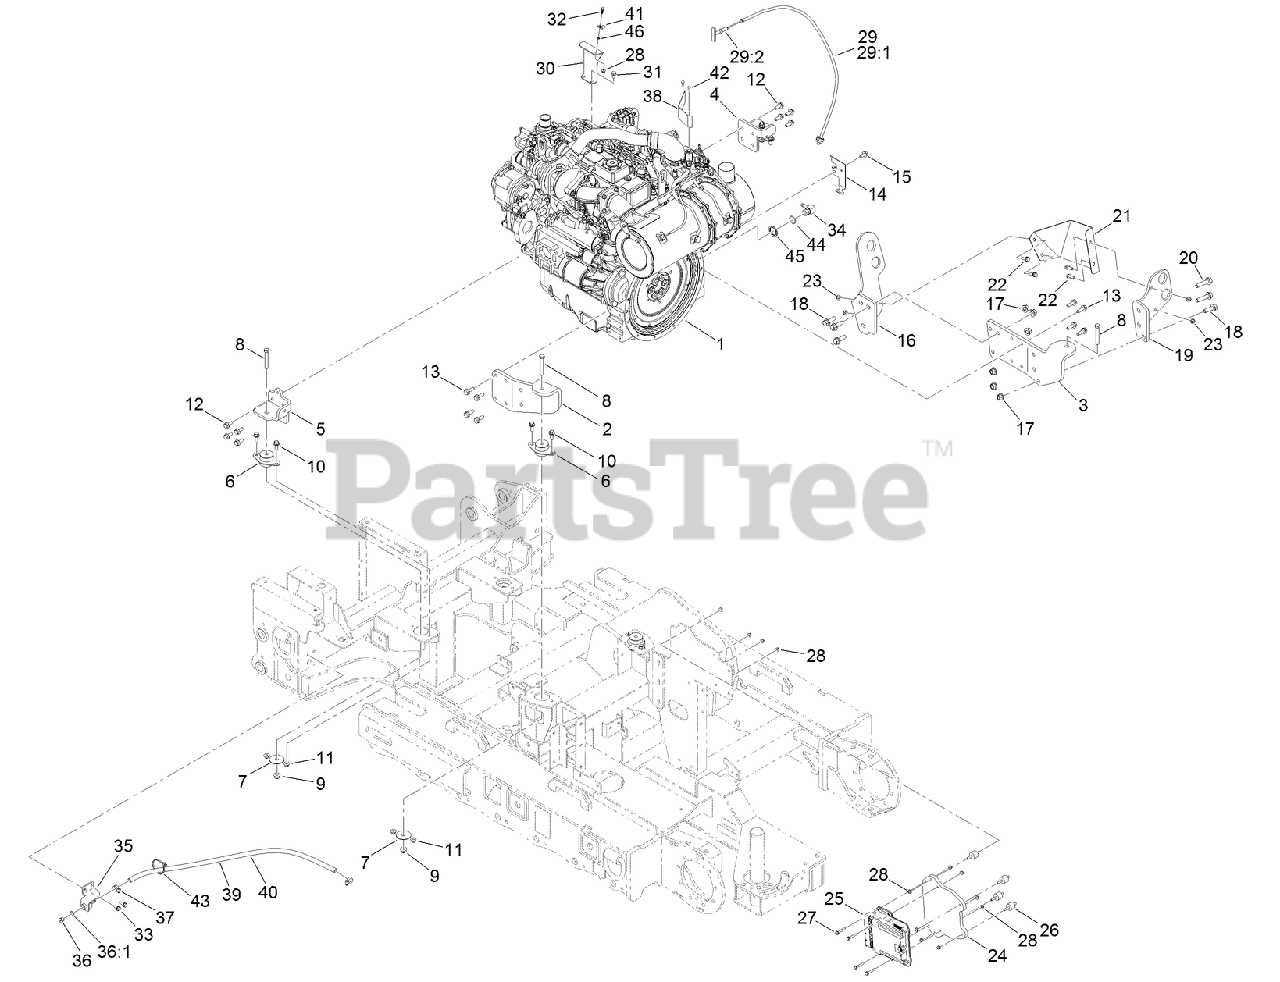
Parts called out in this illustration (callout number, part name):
1	ENGINE ASM
2	BRACKET-ENGINE MOUNT, RH FRONT
3	BRACKET-ENGINE MOUNT, LH FRONT
4	BRACKET, LH REAR
5	BRACKET, RH REAR
7	WASHER-SNUBBING
8	SCREW-HH
9	NUT-HF, NI
10	SCREW-HHF
11	NUT-HF, NI
12	SCREW-HHF
13	SCREW-HHF
14	BRACKET-HARNESS
15	SCREW-HHF
16	BRACKET-BULKHEAD, UPPER
17	NUT-LOCK
18	SCREW-HHF
19	BRACKET-BULKHEAD, LOWER
20	SCREW-HHF
21	BRACKET-SHIELD, HEAT
22	SCREW-HHF
23	NUT-HF, NI
24	PLATE-WEIGHT, ECU
25	CONTROLLER-ENGINE
26	MOUNT-ISOLATOR
27	SCREW-HHF
28	NUT-HF
29	OIL DIPSTICK ASM
29:1	TUBE-DIPSTICK
29:2	DIPSTICK-OIL, ENGINE
30	SHIELD-FUEL HOSE
31	SCREW-HHF
32	SCREW-HHF
33	SCREW-HWH
34	FITTING-BARBED-90
35	PLUG-OIL
36	PLUG-HEX, HOLLOW
36:1	O-RING
37	CLAMP-HOSE
38	PLATE-SENSOR, DPF
39	HOSE-OIL DRAIN
40	CONDUIT-FUEL LINE, SPLIT
41	CLAMP-R
42	SCREW-HHF
43	TIE-CABLE
44	O-RING
45	WASHER-SEAL
46	WASHER-LOCK/EXT
